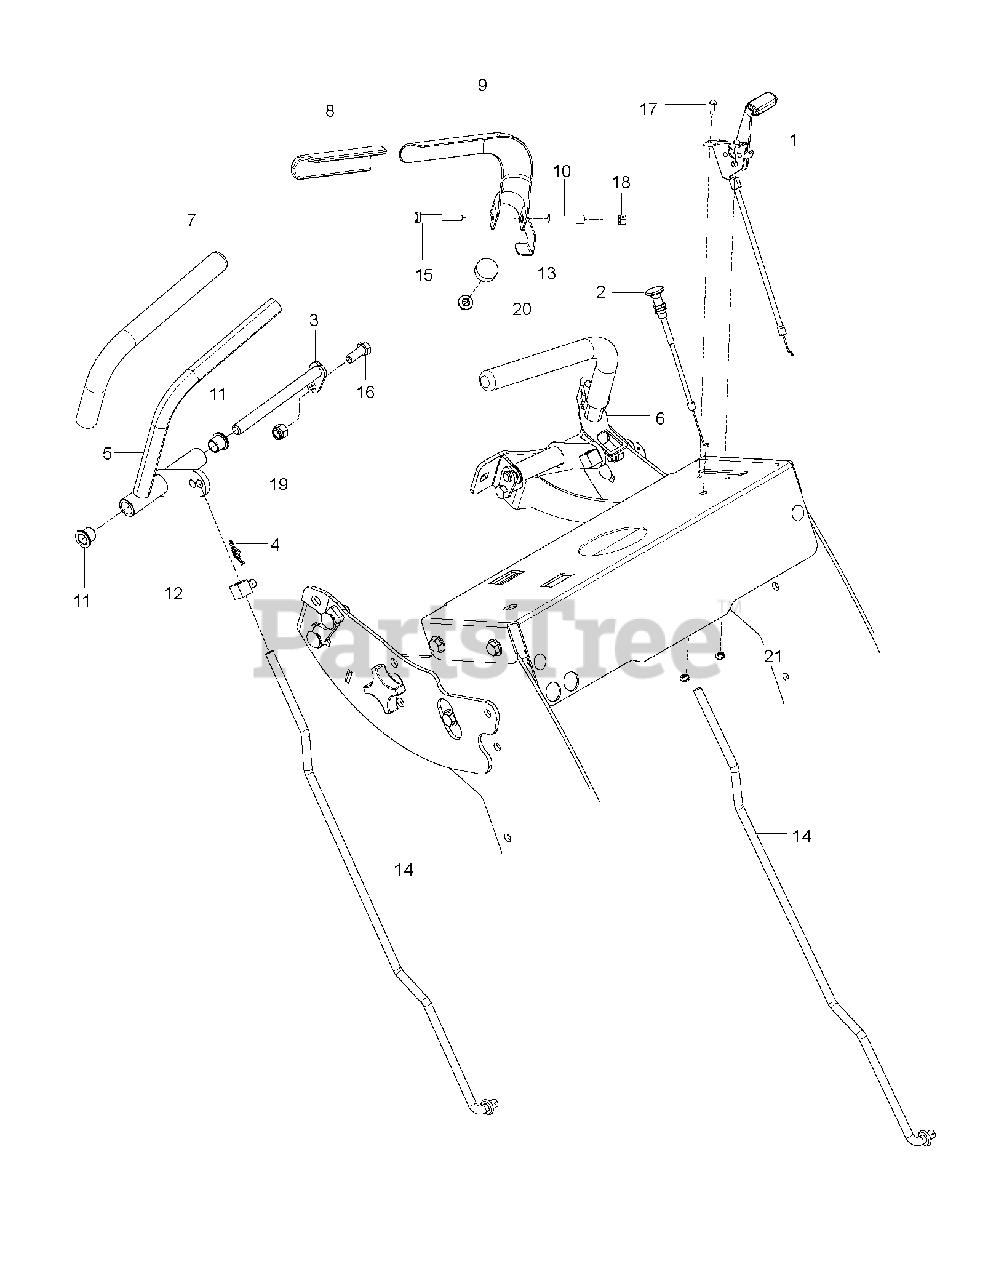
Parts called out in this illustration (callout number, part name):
1	THROTTLE CABLE 00200413
2	CHOKE CABLE 06944700
3	PIN PIN AND LOCK WLDT 203893
4	RING RUE .375 X .054 X 1.254 R
5	DRIVE LINK RH DRIVE LEVER 5 DE
6	DRIVE LINK LH DRIVE LEVER WLDT
7	GRIP CONTROL D18093
8	GRIP GRIP, CLUTCH LEVER, LH AN
9	LEVER, OPERATOR PRESENCE
10	BUSHING OPERATOR PRESENCE 4344
11	BEARING FLG .500 X .625 X .500
12	SWIVEL SWIVEL, 3/8-24
13	BUMPER RUBBER BUMPER 7533600
14	ROD DRIVE TWIN LOOP DBL OFFST
16	BOLT BOLT HEX .38-16 X 1.00 GR
17	SERVICE PARTS SYSTEM SCR-PANHD
18	SERVICE PARTS SYSTEM NUT-LK-CT
19	NUT NUT, 3/8-16 NYLON LOCK ARI
20	SERVICE PARTS SYSTEM NUT-SPNLK
21	SERVICE PARTS SYSTEM NUT-LK-NY
